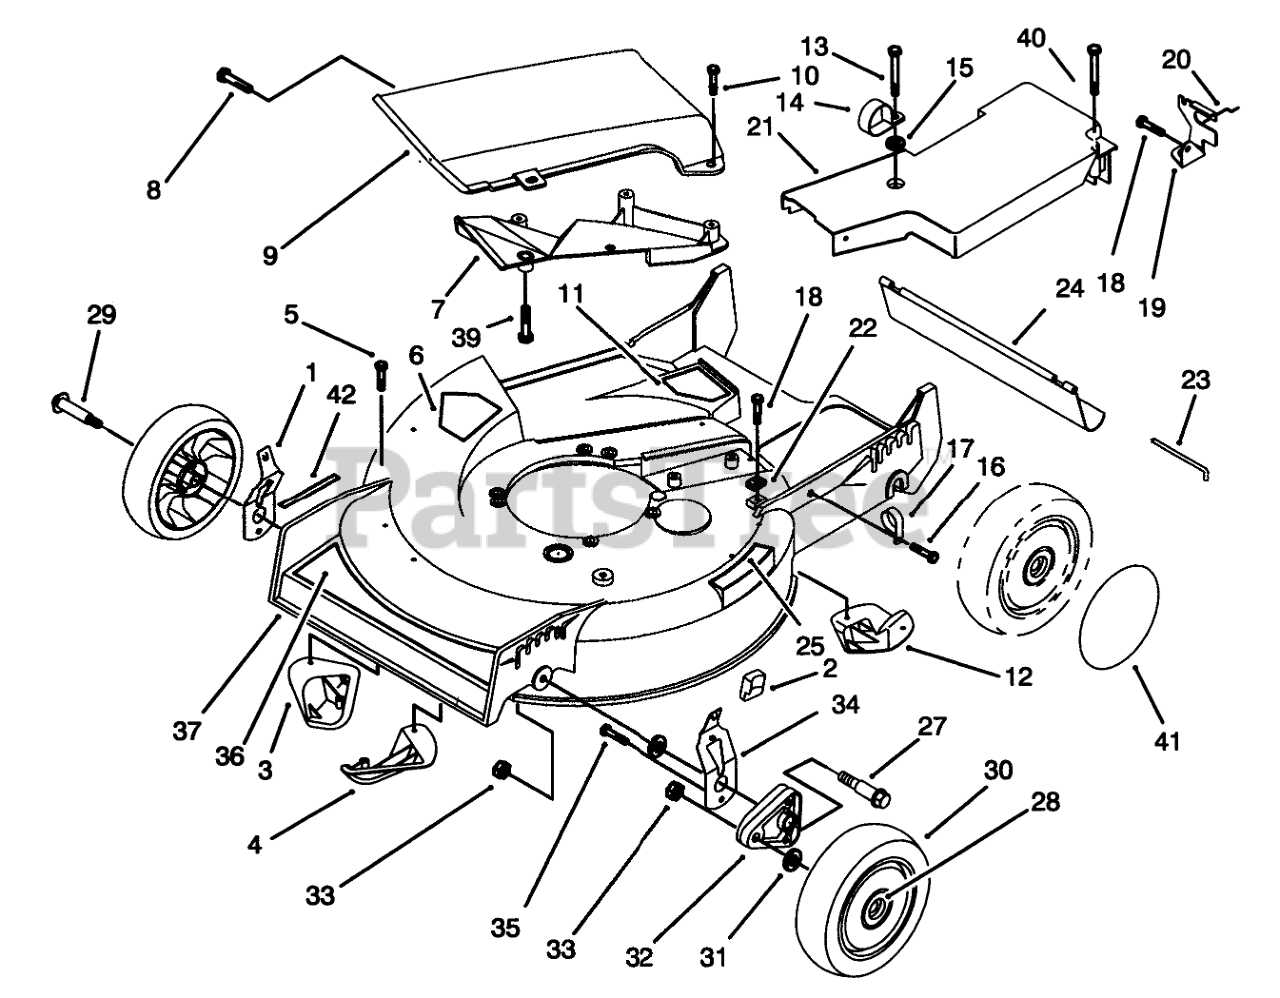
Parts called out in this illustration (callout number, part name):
1	RH SPRING ARM ASM
2	KNOB-ARM
3	KICKER-FRONT
4	KICKER-RH
5	SCREW-PPH
6	DECAL-DANGER
7	Deflector-Recycler
8	SCREW AND WASHER ASM
9	Recycler Cover Assembly (Incl. Ref. #7 & 39)
10	SCREW-HWH
11	DECAL - DANGER
12	KICKER-REAR
13	SCREW-SPECIAL
14	CLAMP-CABLE
15	WASHER
16	SCREW-HWH
17	CLAMP-CABLE
18	SCREW-HWHTF
19	Bracket-Adj. Trac
20	RETAINER-CABLE
21	BELT COVER
22	CLAMP-CABLE
23	ROD-SHIELD
24	SHIELD-TRAILING
25	STEP PAD DECAL
27	BOLT-SHOULDER
28	BUSHING
29	BOLT-WHEEL
30	Wheel & Tire Assembly (Incl Ref. #28)
31	WASHER
32	ARM-PIVOT, FRONT
33	NUT-LOCK
34	LH SPRING ARM ASM
35	SCREW-HWH
36	DECAL - DECK
37	Housing Assembly (Incl. Ref. #3-6, 8, 11, 12 & 42, Pg.1)(Incl . Ref. #5-6, Pg. 3)
39	Screw-Plastite
40	SCREW-HHFTF
41	WHEEL COVER
42	DECAL - HOC
